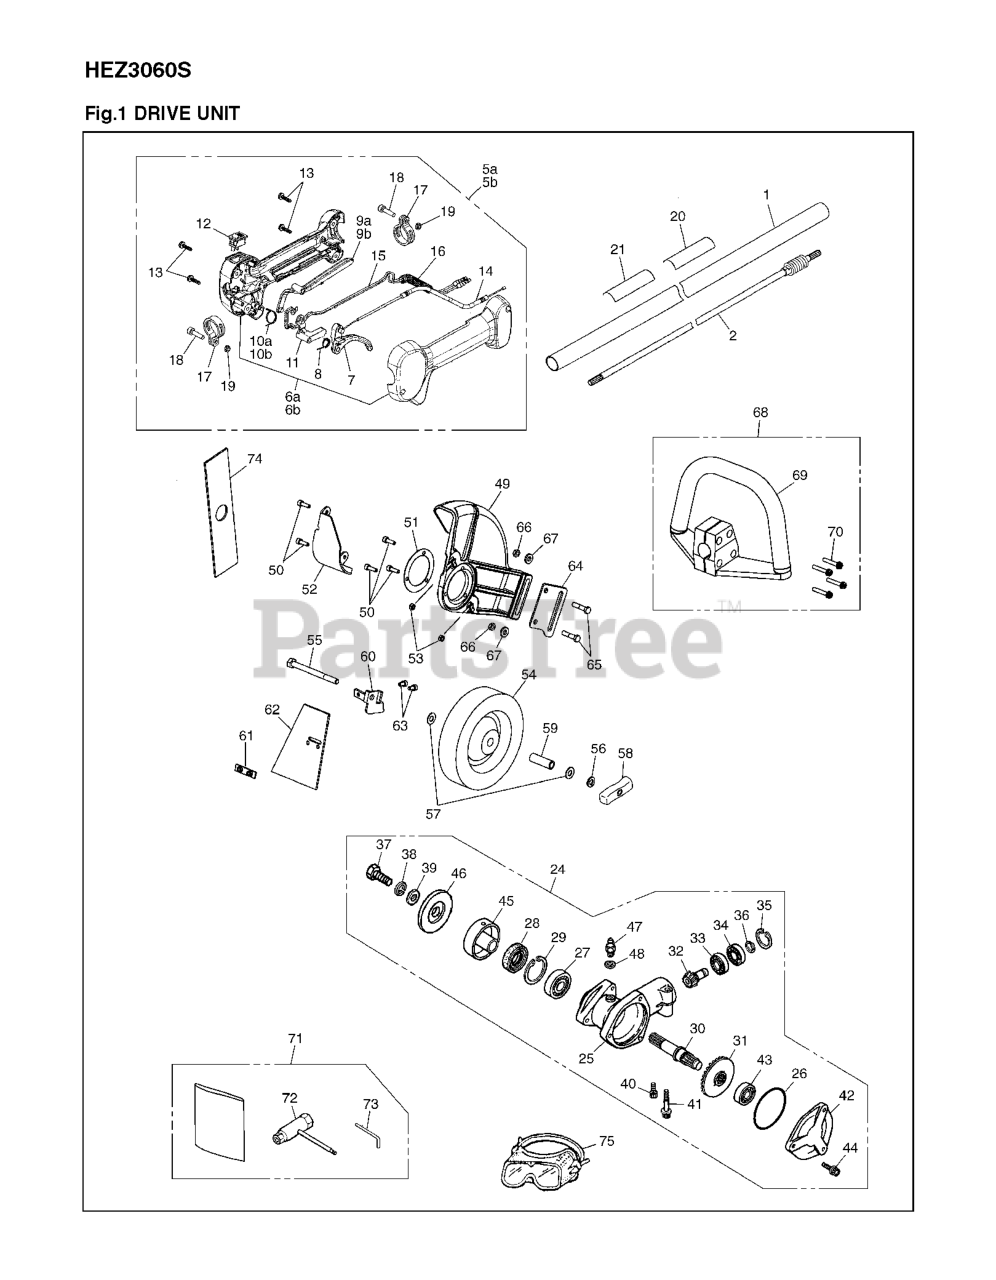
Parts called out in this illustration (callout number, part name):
1	PIPE COMP
5	GRIP ASSY
6	GRIP HALF SET
7	LEVER, THROTTLE
8	SPRING, THROTTLE
9	LEVER FOR GRIP (RPLS -0600)
9	LEVER, SAFETY
10	SPRING JOINT
10	SPRING
11	LEVER JOINT
15	CORD - C
19	NUT
20	NAME LABEL HEZ3060S
21	LABEL CAUTON FOR BC
24	GEARCASE ASSY
25	GEARCASE
28	OIL SEAL
37	BOLT M8 X L25 L/H
40	BOLT, M5 x 12
44	BOLT M5 X L14 ALLEN
45	HOLDER(A)
46	HOLDER (B)
49	GUARD
50	BOLT M5 X L16 ALLEN
52	PROTECTOR
55	BOLT M8 X L65
63	BOLT M5 X L10 ALLEN BOLT
64	MAIN BRACKET
65	BOLT M8 X L40
68	HANDLE ASSY. (RPLS T319514001)
69	HANDLE T
71	TOOL SET
74	Edger Blade
75	GOGGLExxx (RPLS
